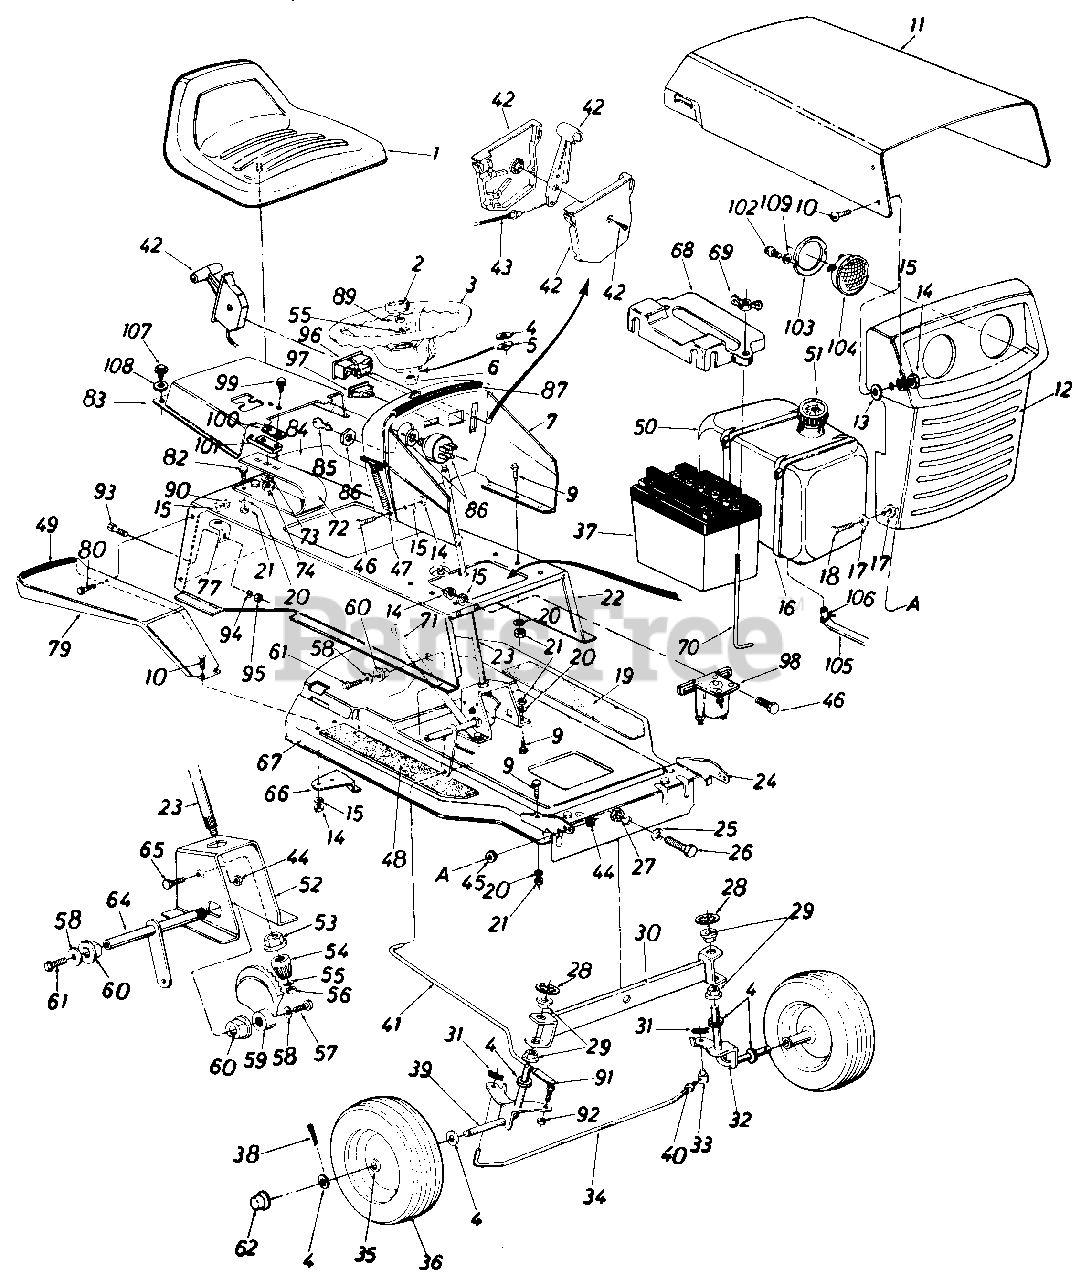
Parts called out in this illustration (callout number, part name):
1	Seat Assembly
2	Cap for Steering Wheel
3	12" Dia. Steering Wheel
4	Fl-Wash. .64 I.D. x 1.12 O.D.
5	Wave Wash. .66 I.D. x .88
6	Hex Flange Brg. .630 I.D.
7	Dash Panel Ass y.
9	Hex Sems Scr. 5/16-18 x .75 Lg.*
10	Truss Mach. Scr. 1/4-20 x .75" Lg.
11	Hood
12	Grille w/Lights
14	Hex Nut 1/4-20 Thd.
15	L-Wash. 1/4" Scr.
16	Cable Tie
17	Flat Wash. .39" I.D. x .87" O.D.
18	Hex Bolt 3/8-16 x 1.0" Lg.
19	Foot Mat-L.H.
20	L-Wash. 5/16" Scr.
21	Hex Nut 5/16-18 Thd.
22	Upper Frame
23	Steering Shaft
24	Front Pivot Bracket
25	L-Wash. 518" Scr.
26	Hex Bolt 5/8-18 x 1.31-Special
27	Hex Jam Nut 5/8-18 Thd.
28	Push Nut .625" Shaft
29	Hex Flange Brg.
30	Pivot Bar Ass'y.
31	Cot-Pin 1/8" Dia. x 1.00" Lg.
32	Axle Ass'y.-Front-L.H.
33	Ferrule
34	Tie Rod
35	Flange Bearing .63 I.D.
36	Front Wheel Ass'y.-Comp. 10.5 x 4.0
37	12V Battery
38	Cot-Pin 1/8" Dia. x 1.25" Lg.
39	Axle Ass'y.-Front-R.H.
40	Hex Jam Nut 3/8-24 Thd.
41	Steering Rod
42	Throttle Control Box Ass'y.
43	Throttle Control Wire
44	Hex Cent. L-Nut 3/8-16 Thd.
45	Spacer
46	Hex Scr. 1/4-20 x .50" Lg.
47	Hood Lock Ass 'y.
48	Foot Mat-R.H.
49	Edge Strip (6.5" Lg.)
50	Gas Tank
51	Gas Gauge
52	Steering Gear Support Brkt.
53	Hex Flange Brg. .50 I.D.
54	Pinion Gear
55	Bell-Wash. .357 I.D. x .88 O.D.
56	Hex Ins. L-Nut 5/16-18 Thd.
57	Hex Scr. 3/8-24 x .75" Lg.
58	Bell-Wash.
59	Bevel Gear
60	Plastic Flanged Brg.
61	Hex Scr. 3/8-24 x .50" Lg.
62	Hub Cap
64	Steering Arm Shaft Ass'y.
65	Hex Scr. Nylon 3/8-16 x 1.25" Lg.
66	Transmission Belt Guard
67	Lower Frame
68	Battery Cover
69	Wing Nut 1/4-2 Thd.
70	Hold-Down Rod
71	Transmission Support Brkt.
72	Seat Spring 3.25 High
73	L-Wash. 1/2" Scr.
74	Hex Nut 1/2-13 Thd.
77	Hitch Bracket
79	Rear Fender
80	Hex Scr. 1/4-28 x .62" Lg.
82	Hex Sems Scr. 5/16-18 x 1.00" Lg.*
83	Transmission Panel
84	Rear Fender
85	Ignition Key Only
86	Ignition Switch
87	Trim Strip 12" Lg.
90	Hex Nut 1/4-28 Thd.
91	Ball Joint Ass'y. 3/8-24 Thd.
92	Hex Ins. L-Nut 3/8-24 Thd.
93	Hex Scr. 3/8-16 x .75" Lg.
94	Lock Washer 3/8" I.D.
95	Hex Nut 3/8-16 Thd.
96	Ammeter
97	Light Switch
98	Solenoid
99	Hex AB-Tap Scr. #8 x .50" Lg.
100	Insulator Nut Plate
101	Spring Switch
102	Hex Wash. Hd. Scr. 1/4" x .62" Lg.
103	Headlight Retainer
104	Headlight
105	Gas Line
106	Hose Clamp
107	Hex Wash. Hd. Scr. 1/4-20 x .50" Lg.
108	Bell-Wash. .265" I.D. x .75"O.D.
109	Flat Wash. .281" I.D. x .625" O.D. x .106
